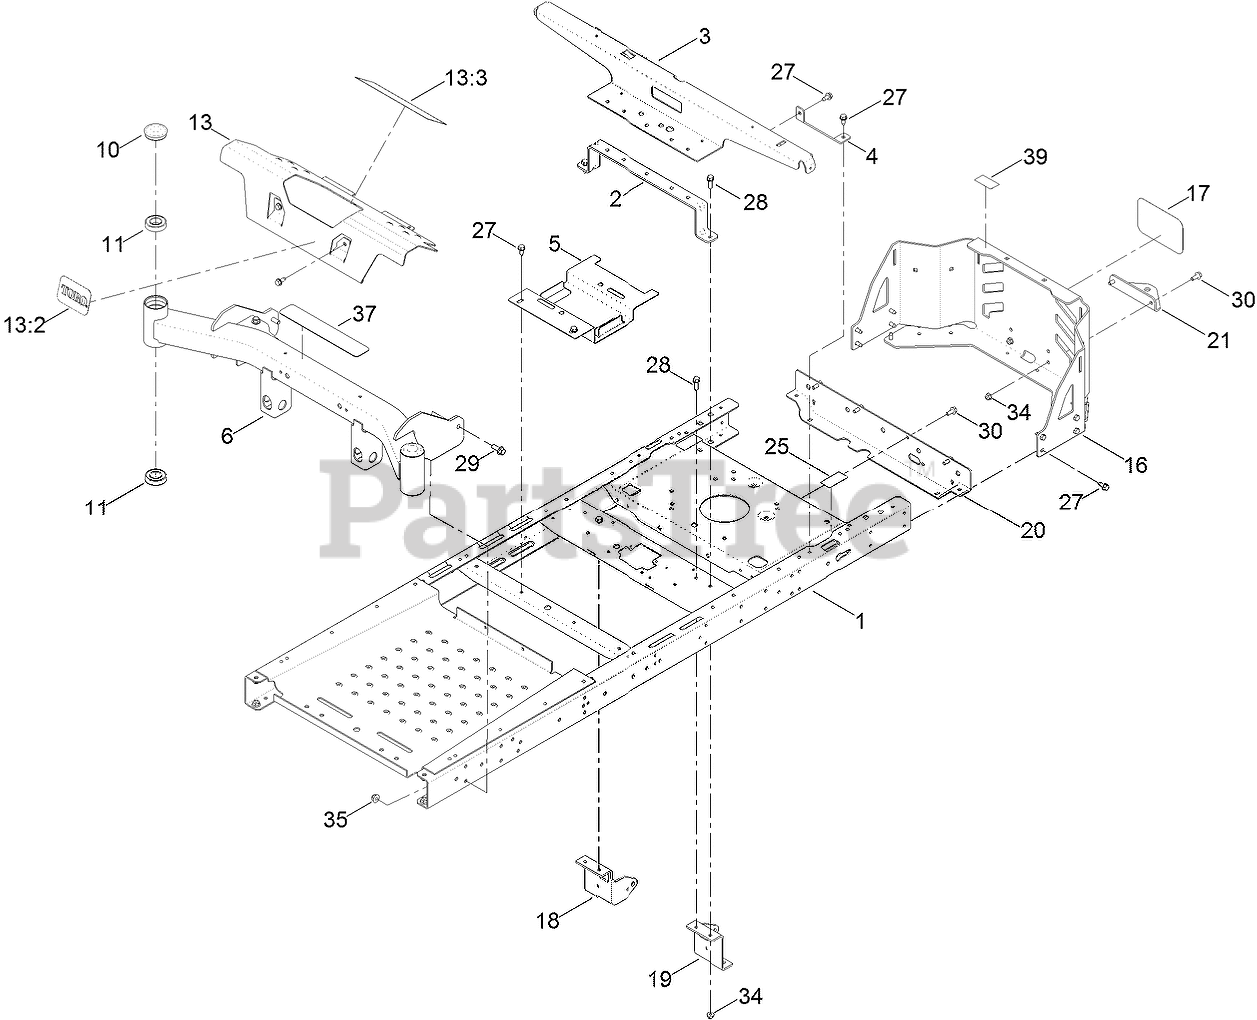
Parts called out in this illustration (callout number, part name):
1	RIVETED FRAME ASM (WIDE LEVER)
2	BRACE-SEAT, REAR (WIDE)
3	SUPPORT-POD
4	SUPPORT-TANK, REAR
5	BRACKET-BATTERY
6	FRONT AXLE ASM
10	CAP-GREASE
11	BEARING-BALL
13	FOOTREST
13:3	DECAL-DANGER
16	GUARD-ENGINE
17	DECAL
18	MOUNT-HYDRO, FRONT (RH)
19	MOUNT-HYDRO, FRONT (LH)
20	CROSSMEMBER-REAR, WIDE
21	BRACKET-HITCH
25	DECAL-BYPASS
27	SCREW-HWHTF
28	SCREW-HHF
29	SCREW-HHF
30	SCREW-HHF
34	NUT-HF, NI
35	NUT-HF, NI
37	TREAD-STEP
39	DECAL-BUCKET
